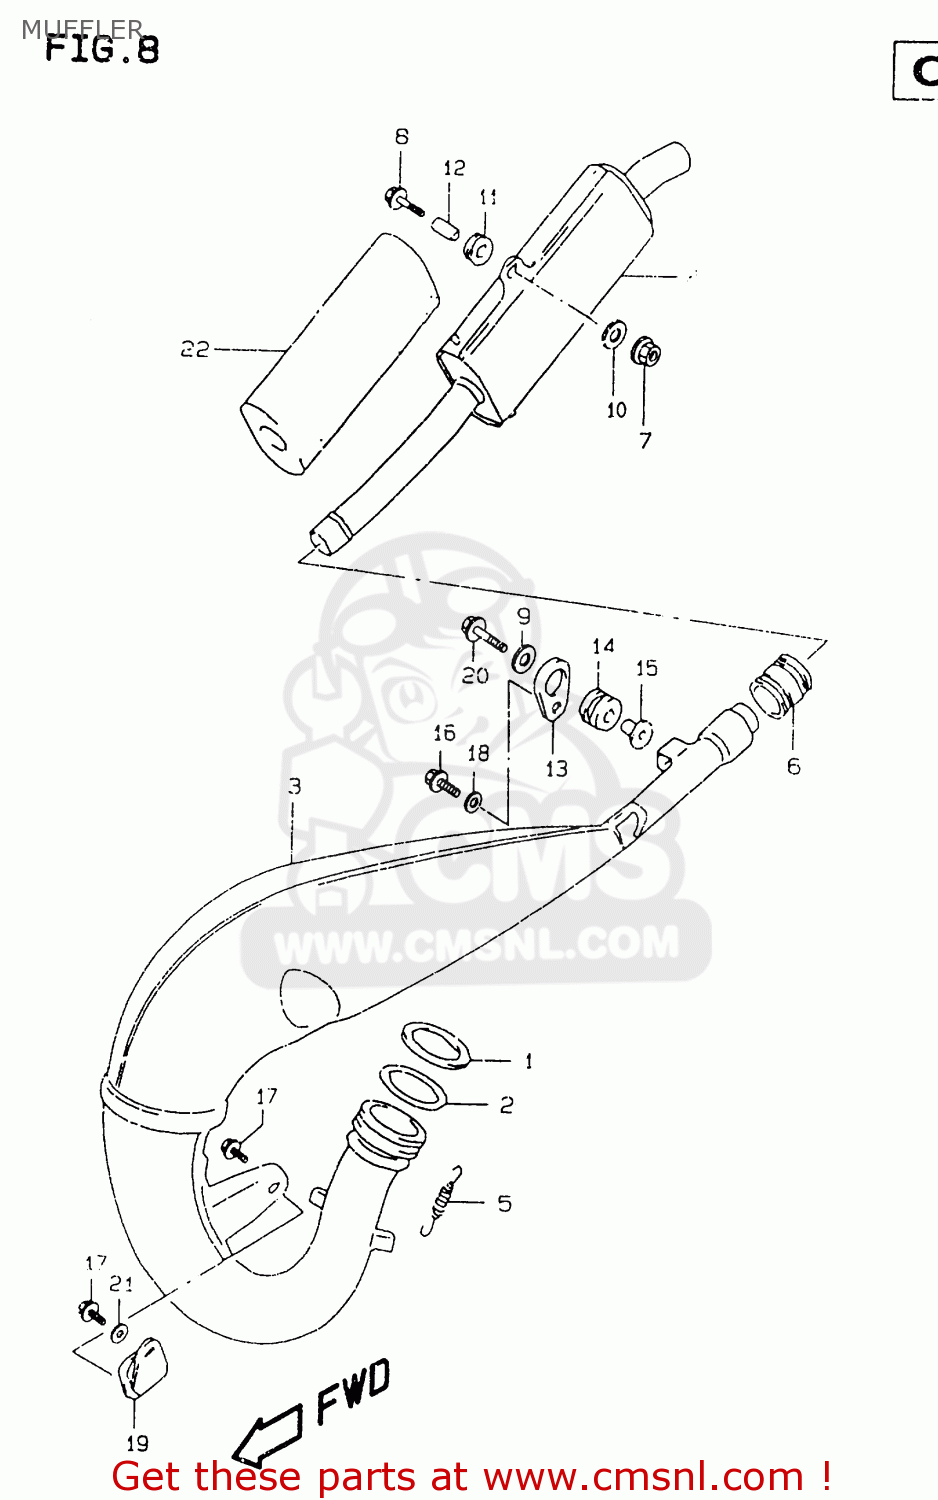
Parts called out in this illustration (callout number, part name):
1	WASHER,EXHAUST PIPE
2	O RING,EXHAUST PIPE
3	BODY,MUFFLER 1ST
4	BODY MUFFL. 2N
5	SPRING
6	CONNECTOR,SECOND MUFFLER
7	NUT
8	BOLT,G/S SWITC
9	WASHER(6.5X24X1.2)
10	WASHER(6.5X24X1.2)
11	CUSHION
12	SPACER(6.5X11.5X12)
13	PLATE,MUFFLER MTG
14	CUSHION,MUFFLER
15	SPACER,MUF MTG
16	SCREW
17	BOLT
18	WASHER
19	DAMPER,MUFFLER SUPPORT
20	BOLT
21	WASHER
22	SILENCER,MUFFLER
